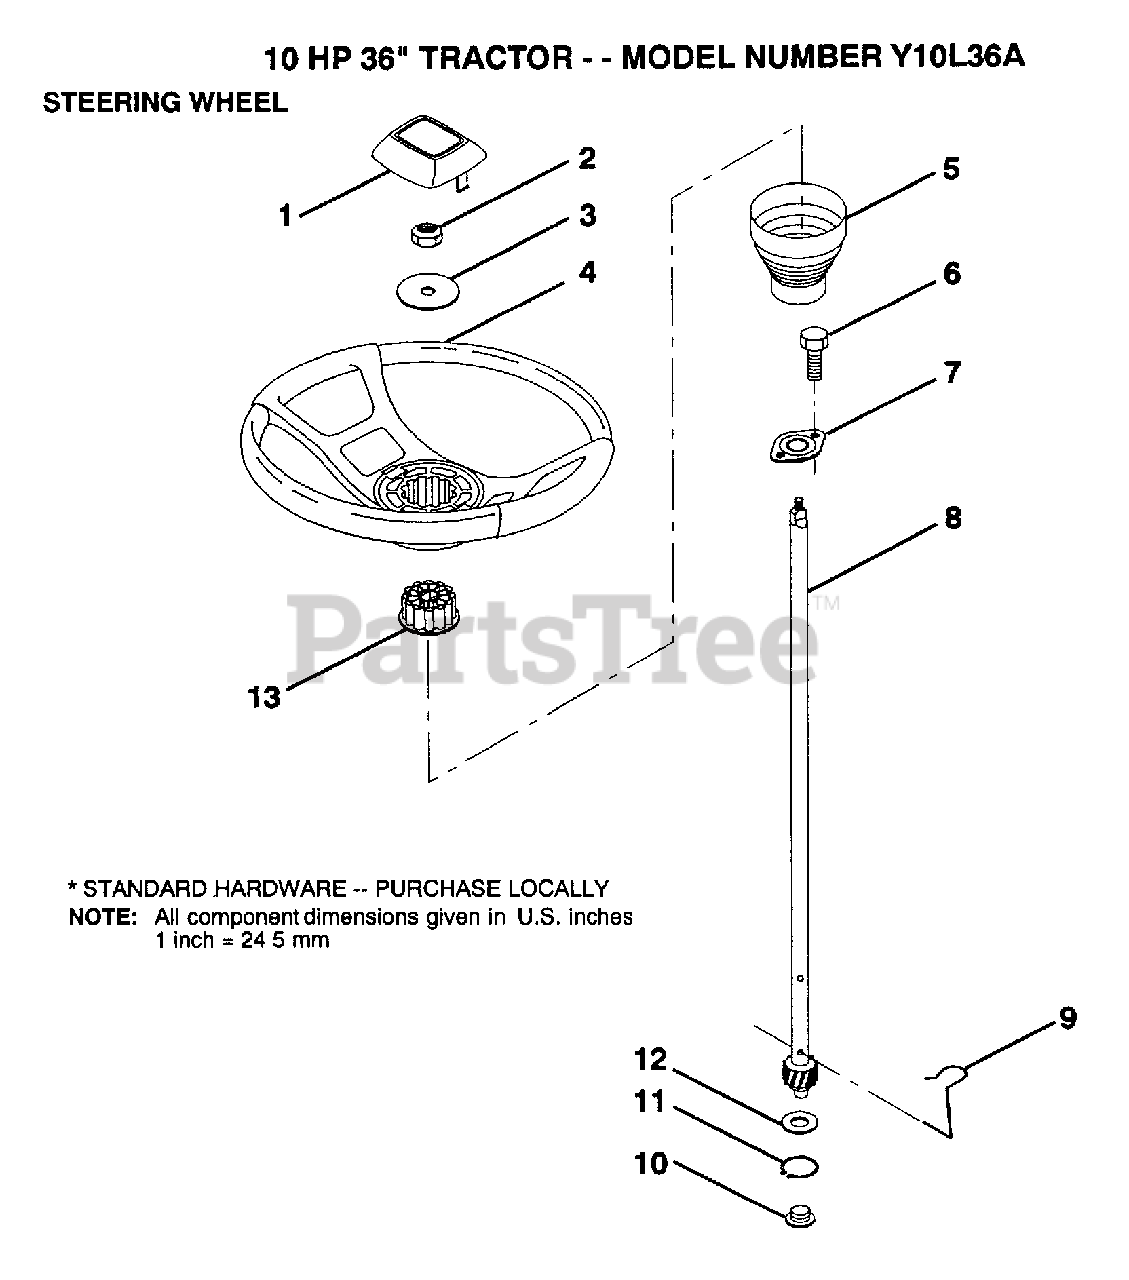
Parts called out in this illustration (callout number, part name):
1	ST WHL INSERT CAP
2	GRIPCO NUT
3	WASHER T
5	SLEEVE STEERING
9	STEERING CLIP
10	BUSHING STEER LWR
11	RING
12	WASHER LT
13	ADAPTER-WHEEL LT
